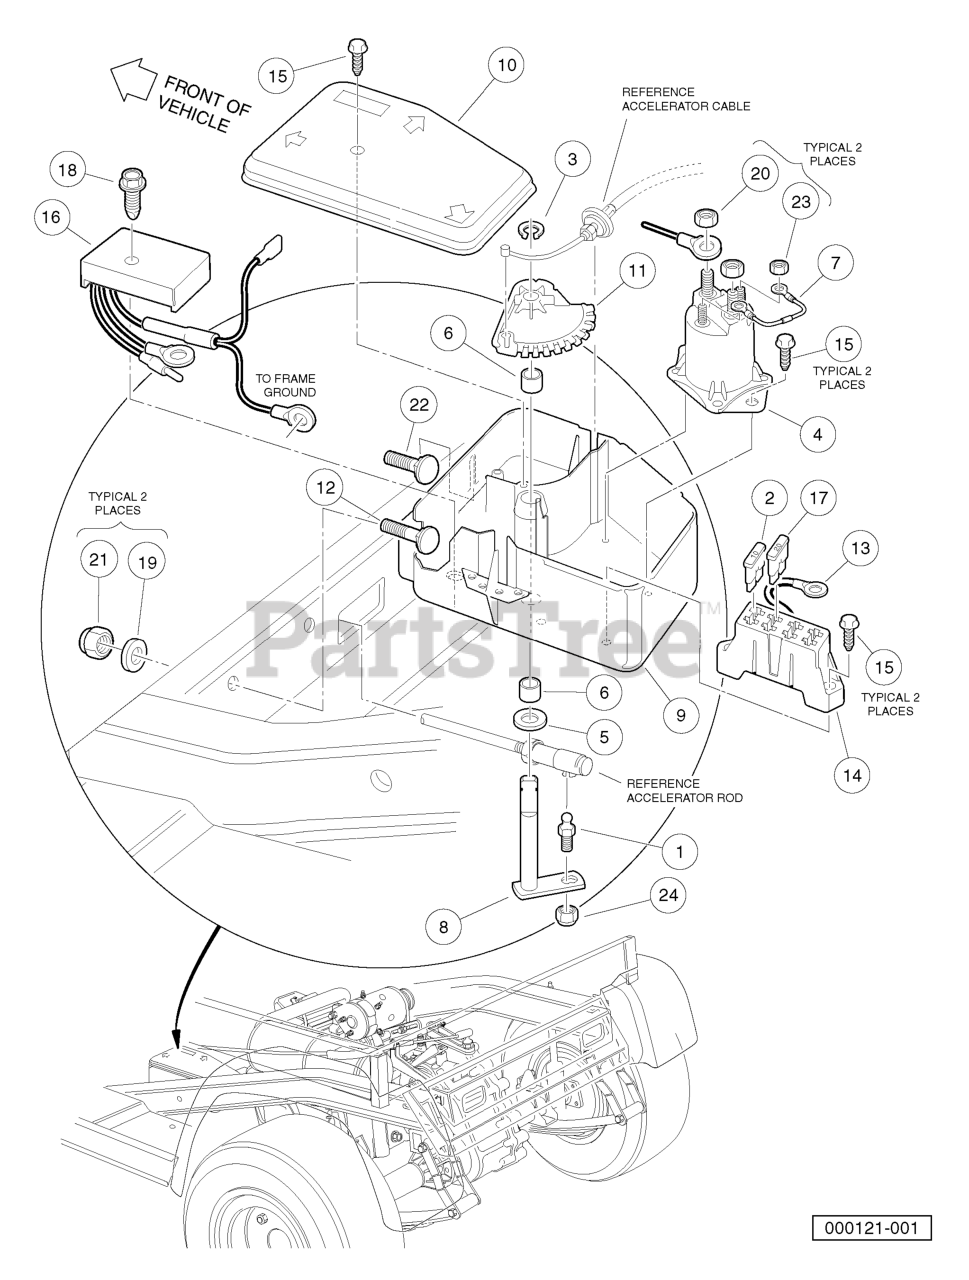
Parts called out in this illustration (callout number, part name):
2	10 AMP FUSE
4	SOLENOID, 12 VOLT
6	BUSHING, SECONDARY WGHT SPLIT
7	ASM, DIODE
8	BELL CRANK AND SHAFT ASSY
9	BOX, ELECTRICAL COMPONENT
10	COVER, OHV ELECTRIC BOX
11	CAM, ELECTRIC BOX
12	BOLT,5/16-18 X 2.0 RD HD SQ NK
13	WIRE ASSY, #10 RED
14	FUSE BLOCK
15	SCREW, #12-16 X .625 HI-LO
17	FUSE - 20 AMP
18	SCREW, 1/4-15 X .50 HI-LO HEX
19	WASHER, 5/16 TYPE A FLAT
20	NUT, 5/16-18 HEX
21	LOCKNUT, 5/16-18 NYLON INSERT
22	BOLT 5/16-18 X 1.5
23	NUT, #10-32 HEX
24	LOCKNUT, 1/4-28 NYLON INSERT
